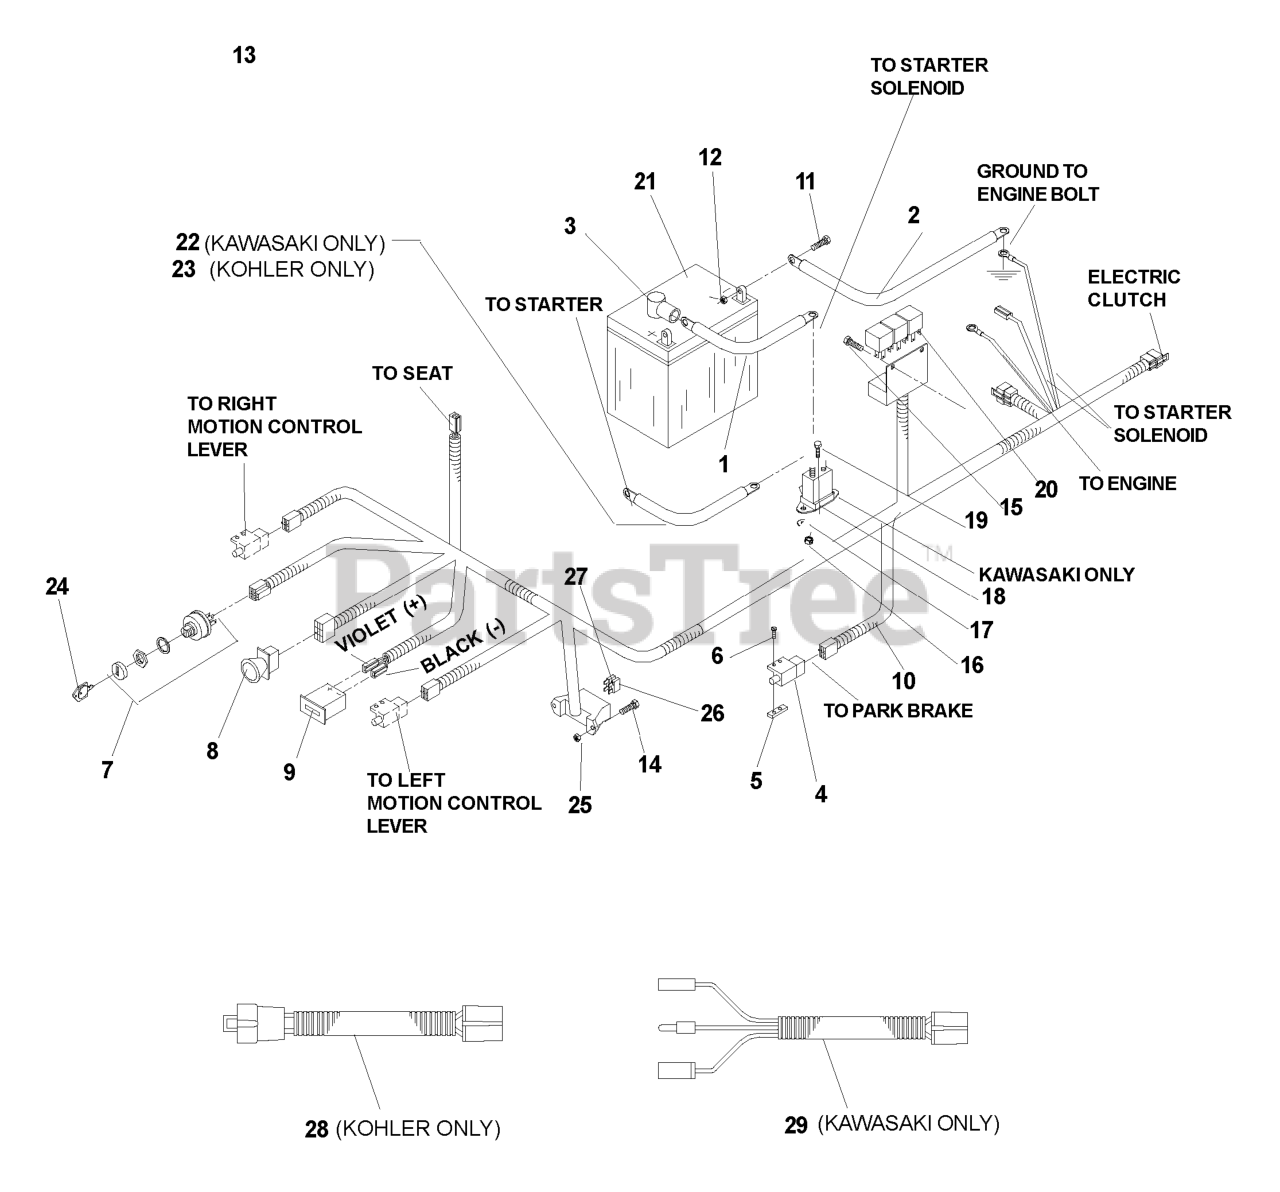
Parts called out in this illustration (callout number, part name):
1	CABLE POSITIVE, LONG
2	CABLE-NEGATIVE
4	SWITCH, INTERLOCK
5	TAPPED PLATE
6	SCREW #10-24 X 5/8
7	RP IGNITION SWITCH
8	RP.SWITCH, BLADE
9	HOUR METER
10	FRAME HARNESS
11	HCS 5/16C X 3/4
12	NUT 5/16 NYLOC
13	NUT 10-24 NYLOC
14	SCREW, #1--24 X 1/2 SLOTTED
15	SCREW #10 X 1/2 SELF TAPPING
16	NUT 1/4C CENTERLOCK
17	WASHER 1/4 INT TOOTH
18	SOLENOID
19	HCS 1/4C X 5/8
21	BATTERY, 12 V 330 AMP
22	POST.CABLE LONG
23	CABLE POSITIVE
24	KEY
25	NUT 10-24 NYLOC
26	FUSE, 7.5 AMP 32 VOLT ATO
27	FUSE, 20 AMP 32 VOLT ATO
28	KOH PIGTAIL
29	KAW PIGTAIL
